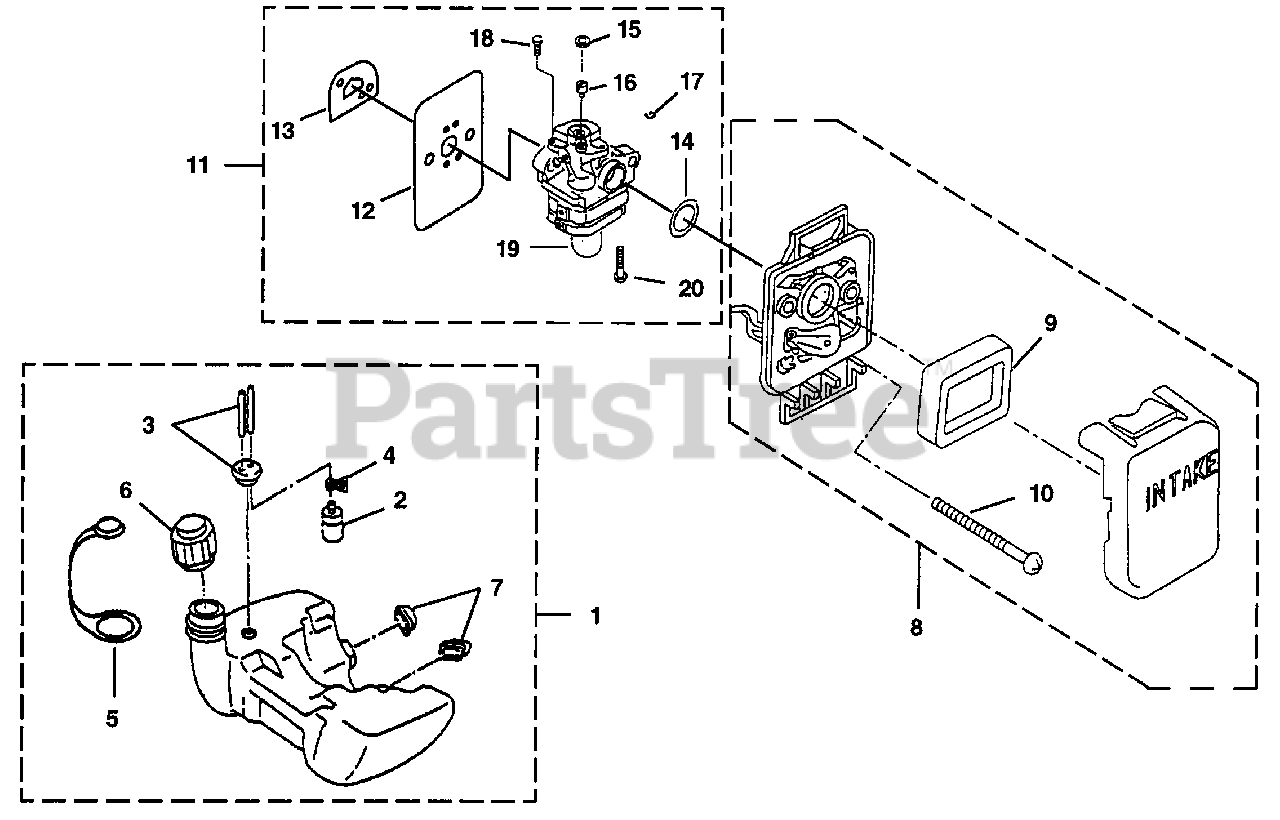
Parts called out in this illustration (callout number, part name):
1	FUEL TANK ASSEMBLY
2	FILTER-Fuel
4	CLAMP-Hose
5	CAP-Retainer
6	CAP-Fuel
7	RUBBER BUMPER KIT
8	AIR FILTER ASSEMBLY
9	FILTER-Air
10	SCREW ASSEMBLY (M5 x 14)
11	CARBURETOR ASSEMBLY
12	GASKET-Carburetor
13	GASKET-Heat Dam
14	RING-Packing
16	SWIVEL-Throttle Cable
19	PUMP-Primer
20	SCREW-Primer Cover
